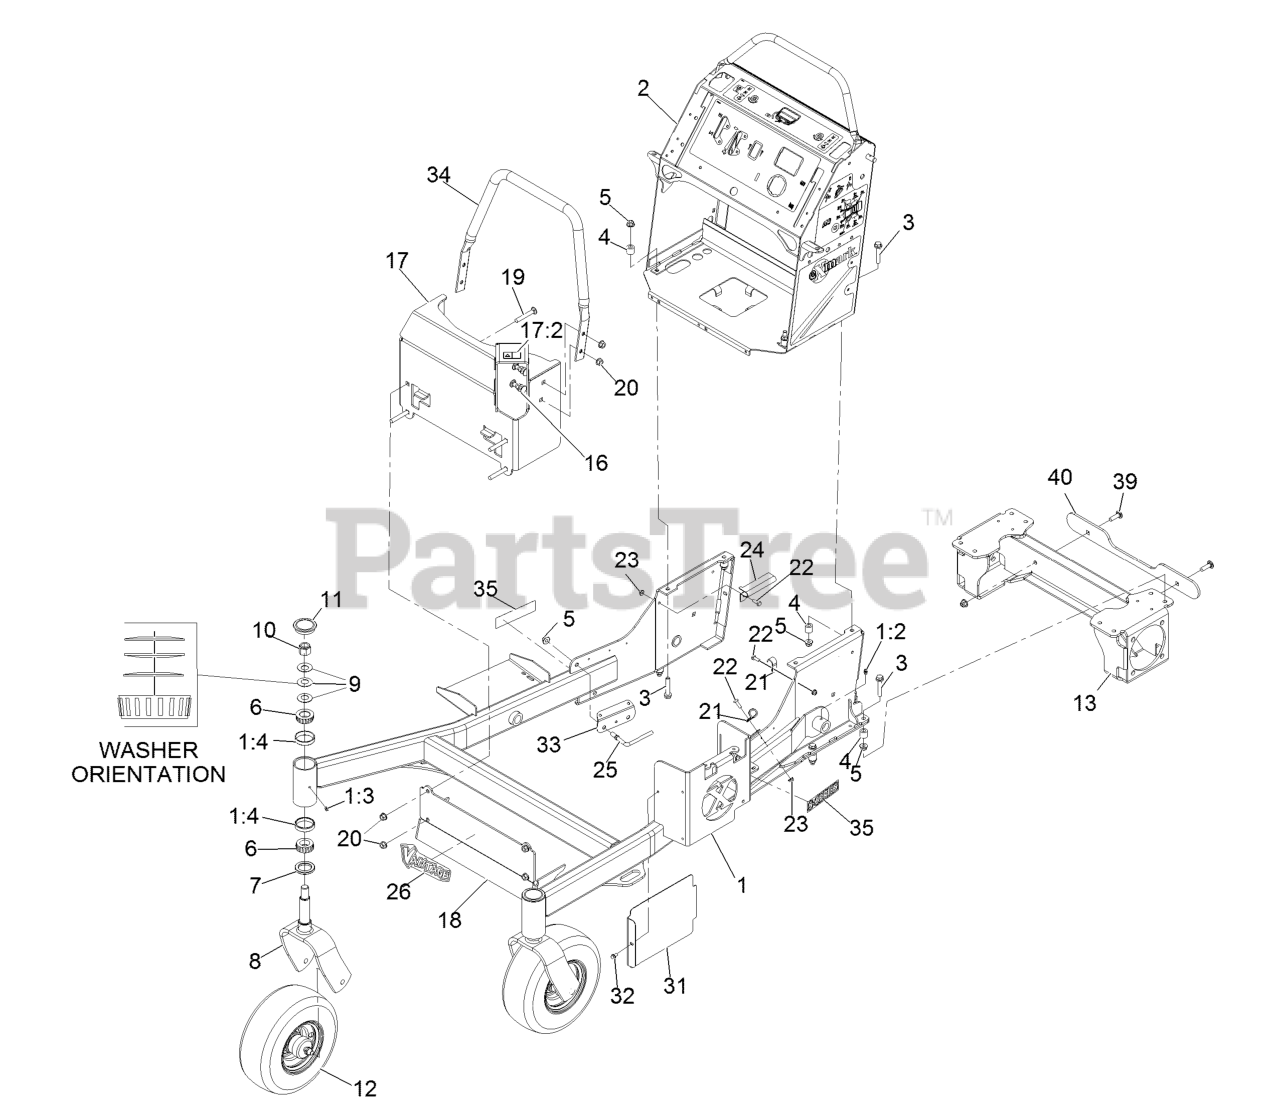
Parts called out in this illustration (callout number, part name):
1	FRONT FRAME ASM
1:2	FITTING-GREASE
1:4	CUP-BEARING
2	CONTROL TOWER ASM-EFI
3	SCREW-HHF
5	NUT-HF, NI
6	Cone-Bearing Tapered Roller
7	SEAL-GREASE
8	FORK-CASTER
9	WASHER-BELLVILLE
10	NUT-LOCK, NI
11	CAP-GREASE
12	WHEEL/TIRE AND BEARING AS
13	MOTOR FRAME WELDMENT
16	SCREW-CARR
17:2	DECAL-WARNING
18	PANEL-GUARD
19	SCREW-CARR
21	CLAMP-CABLE
22	SCREW-HH
24	BRACKET-HOSE, FUEL
25	GUIDE-HOSE, SUPPORT
26	DECAL-VANTAGE LOGO
31	SHIELD-HEAT, TALL
32	SCREW-HWH
33	GUARD-HOSE
34	TUBE-GUARD
35	DECAL-S-SERIES
39	SCREW-CARR
40	PLATE, BUMPER SPACER
